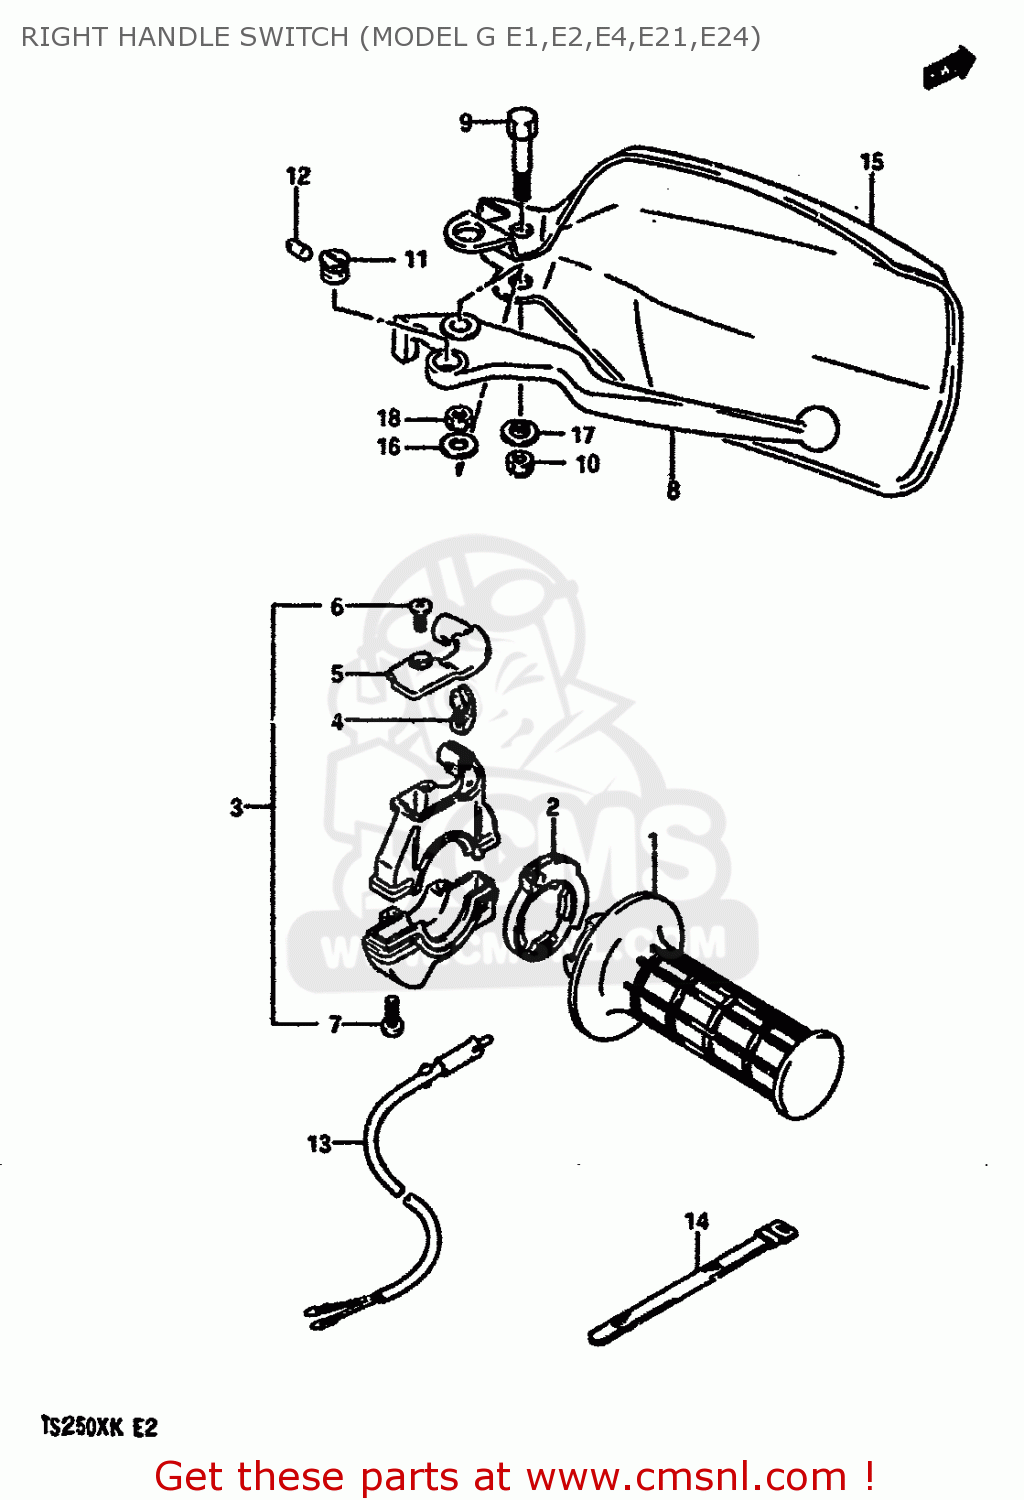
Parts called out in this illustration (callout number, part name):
1	GRIP,THROTTLE
2	ROTOR,THROTTLE GRIP
3	CASE ASSY,THROTTLE
4	GUIDE PIECE,THROTTLE
5	COVER,THROTTLE CASE
6	SCREW
7	SCREW
8	LEVER,BRAKE
9	BOLT,LEVER PIVOT
10	NUT 6MM
11	ADJUSTER
12	ROD,PUSH
13	SWITCH ASSY,STOP
14	CLAMP(L:120)
15	COVER,KNUCKLE,RIGHT
16	WASHER(6.5X16X1.2)
17	WASHER
18	NUT 6MM
